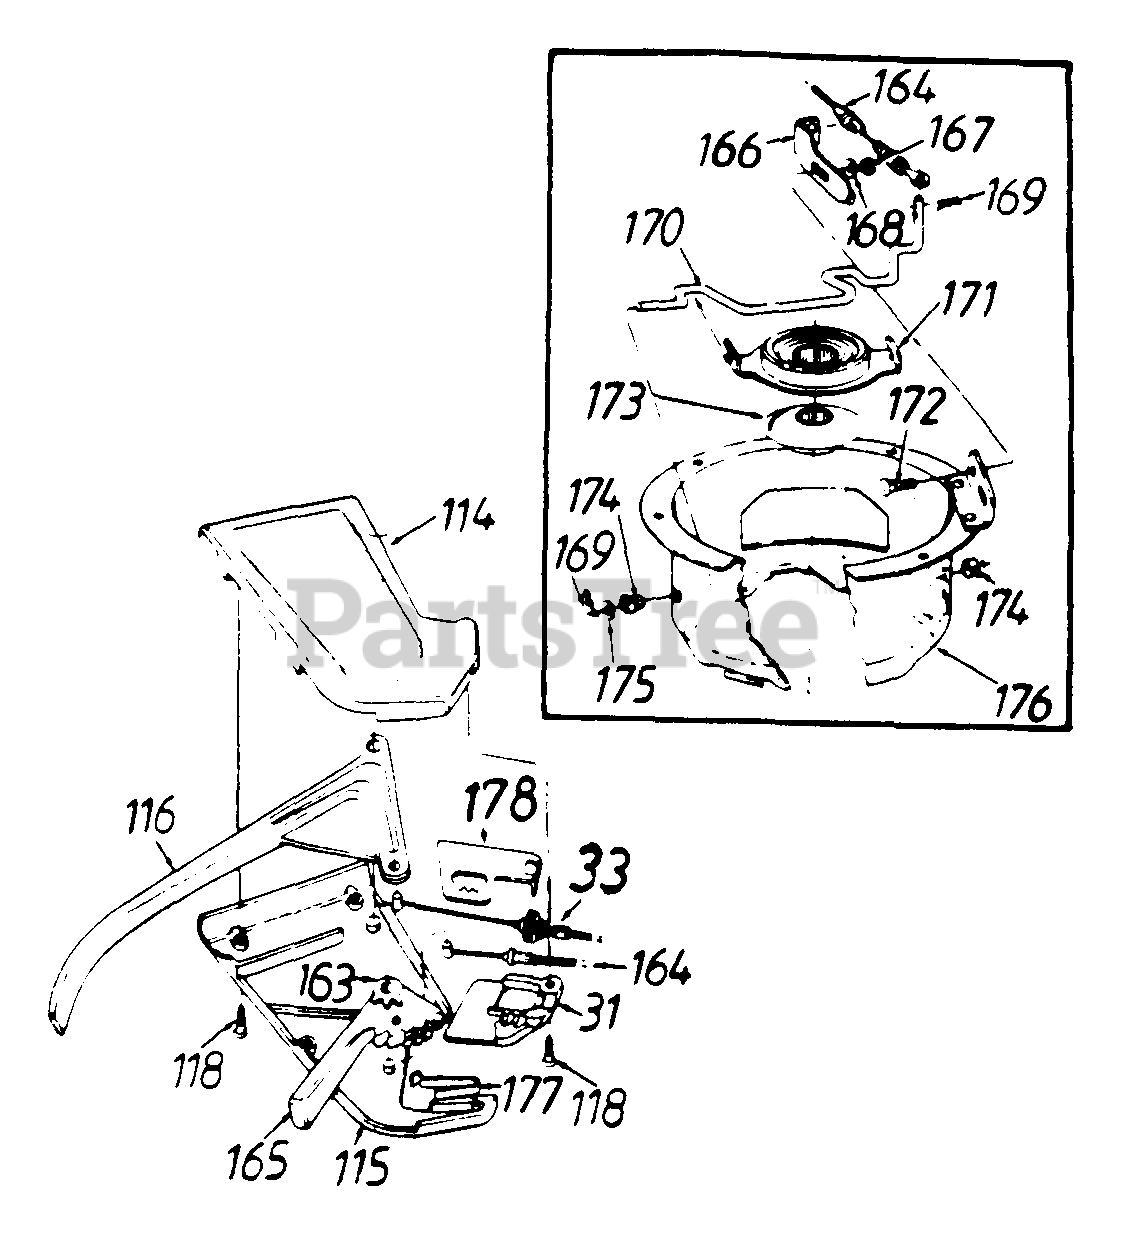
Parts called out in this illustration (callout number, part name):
31	S P. Control Cover
114	Self-Propelled Control Cover
115	Self-Propelled Control Cover
116	Control Lever
118	Fl-"C"-Sunk Hd. Tap Scr. #10 x .75" Lg.
163	3 Tooth Rack Gear Insert
164	Spd. Control Cable - 50" Lg.
165	6-Spd. Shift Lever
168	Hex Cent. L-Nut 1/4-20 Thd.
169	Cot-Pin 3/32" Dia. x .75" Lg.
170	Shift Rod
171	Movable Pulley Half Ass'y.
172	Carr. Bolt 1/4-20 x .50" Lg.
173	Spined Pulley Half
174	Flanged Bushing
175	Fl-Wash..328" I.D. x .68" O.D.
176	Cable Mtg. Brkt. Ass'y.
177	Shift Lever Spring
178	6-Speed Rack Cable Brkt.
